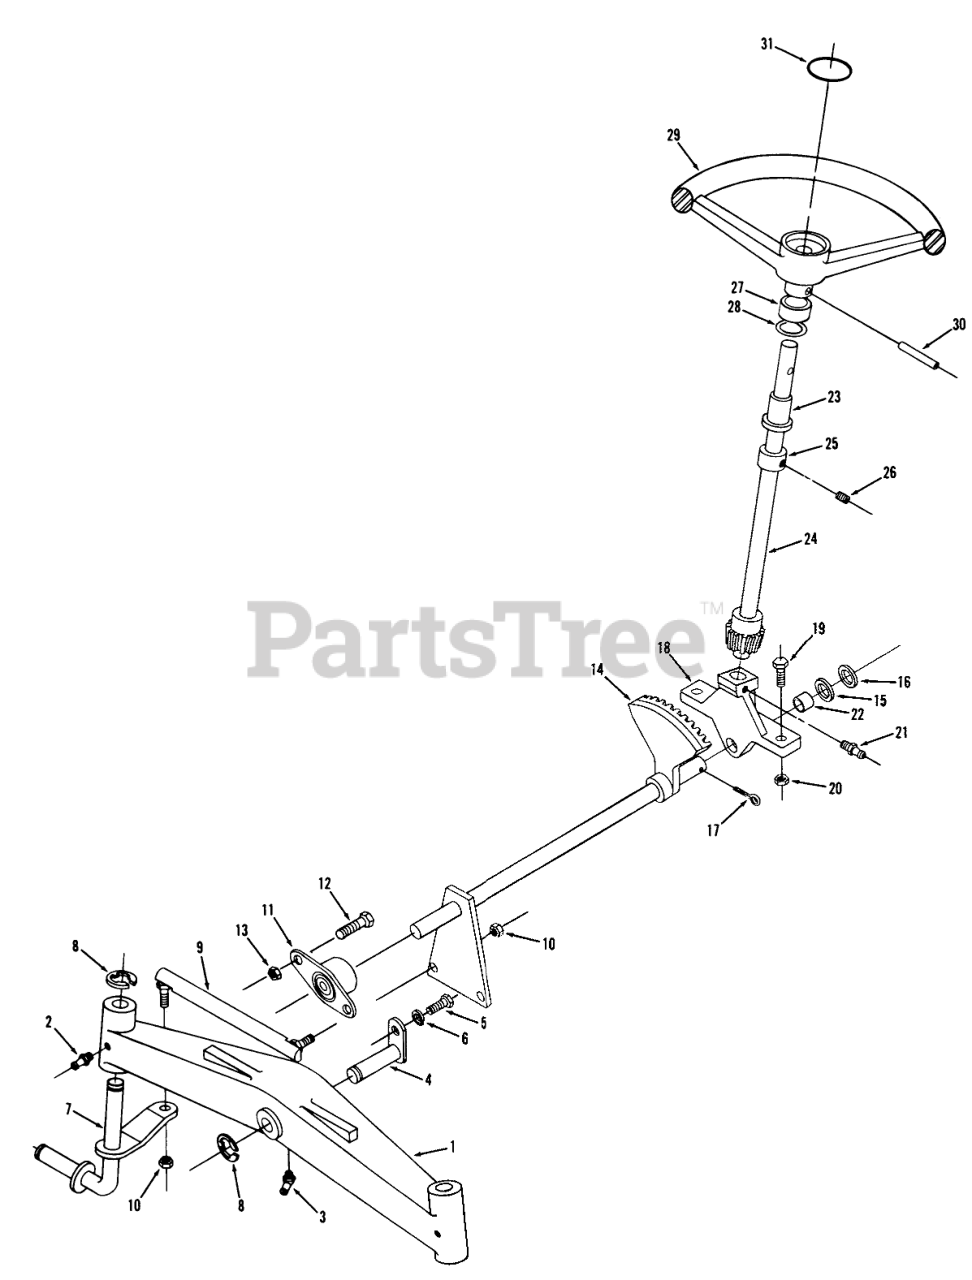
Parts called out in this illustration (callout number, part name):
1	AXLE-FRONT
2	Zerk
3	FITTING-GREASE
4	PIN AND PLATE ASM
5	H H C S
6	Lockwasher
7	Front Spindle LH
7	Front Spindle RH
8	E-RING
9	Tie Rod RH
9	Tie Rod LH
10	NUT-6
11	BEARING-FLANGED
12	BOLT
13	Nut
14	Assy-Steering
15	WASHER-SHIM
16	WASHER
17	PIN-4
18	Support
19	Bolt
20	Nut
21	Zerk
22	BEARING-BRONZE
23	BEARING
24	Upper Steering Shaft
25	Collar
26	SCREW-SET
27	Collar
28	WASHER-BOWED
29	STEERING WH 13" SOFT
30	Pin-Roll
31	STEERING WHEEL INSE
